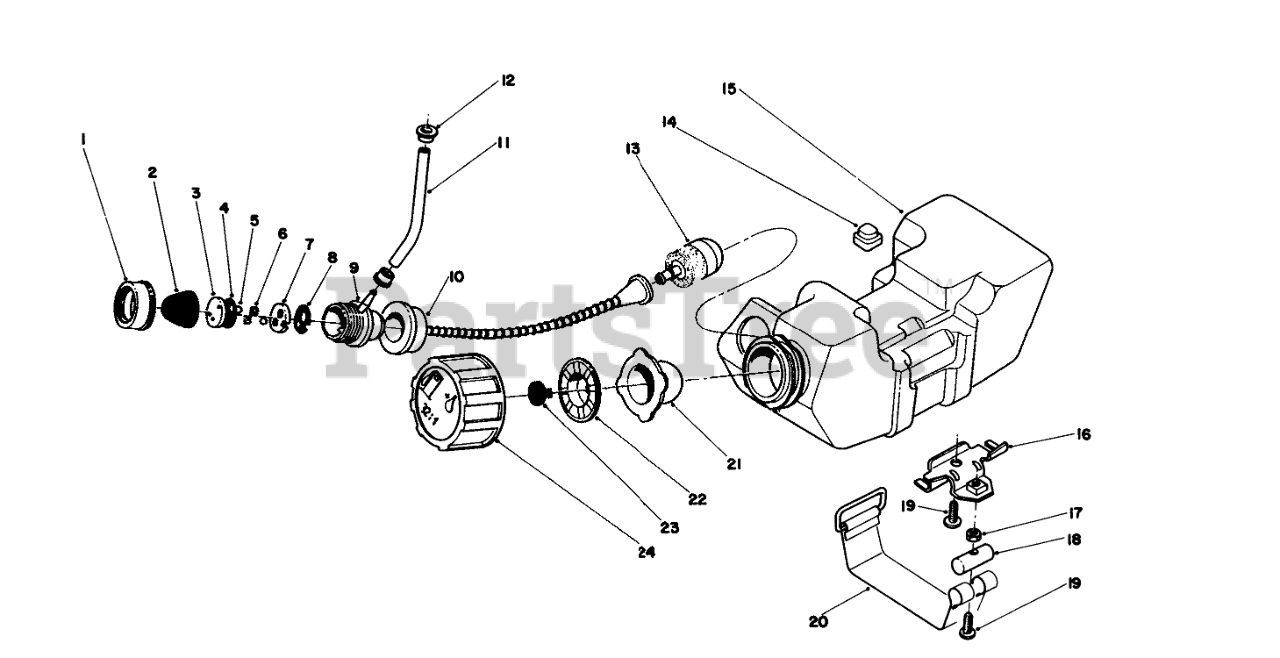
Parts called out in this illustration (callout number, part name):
1	PUMP CAP
3	SEAT VALVE
4	GASKET
6	SPONGE
7	SEAT VALVE
8	GASKET
9	Pump-Primer (Incl. Ref. #2-8)
10	HOSE, SUCTION
11	Tube-Fuel
13	Filter-Fuel
15	Fuel Tank Assembly (Incl. Ref. #1-10, 13, 21-24)
16	HANGER, TANK
19	Screw
20	BAND, TANK
21	GASKET - PACKING
22	HOLDER
23	BREATHER VALVE
24	Tank Cap Assembly (Incl. Ref. #21-23)
